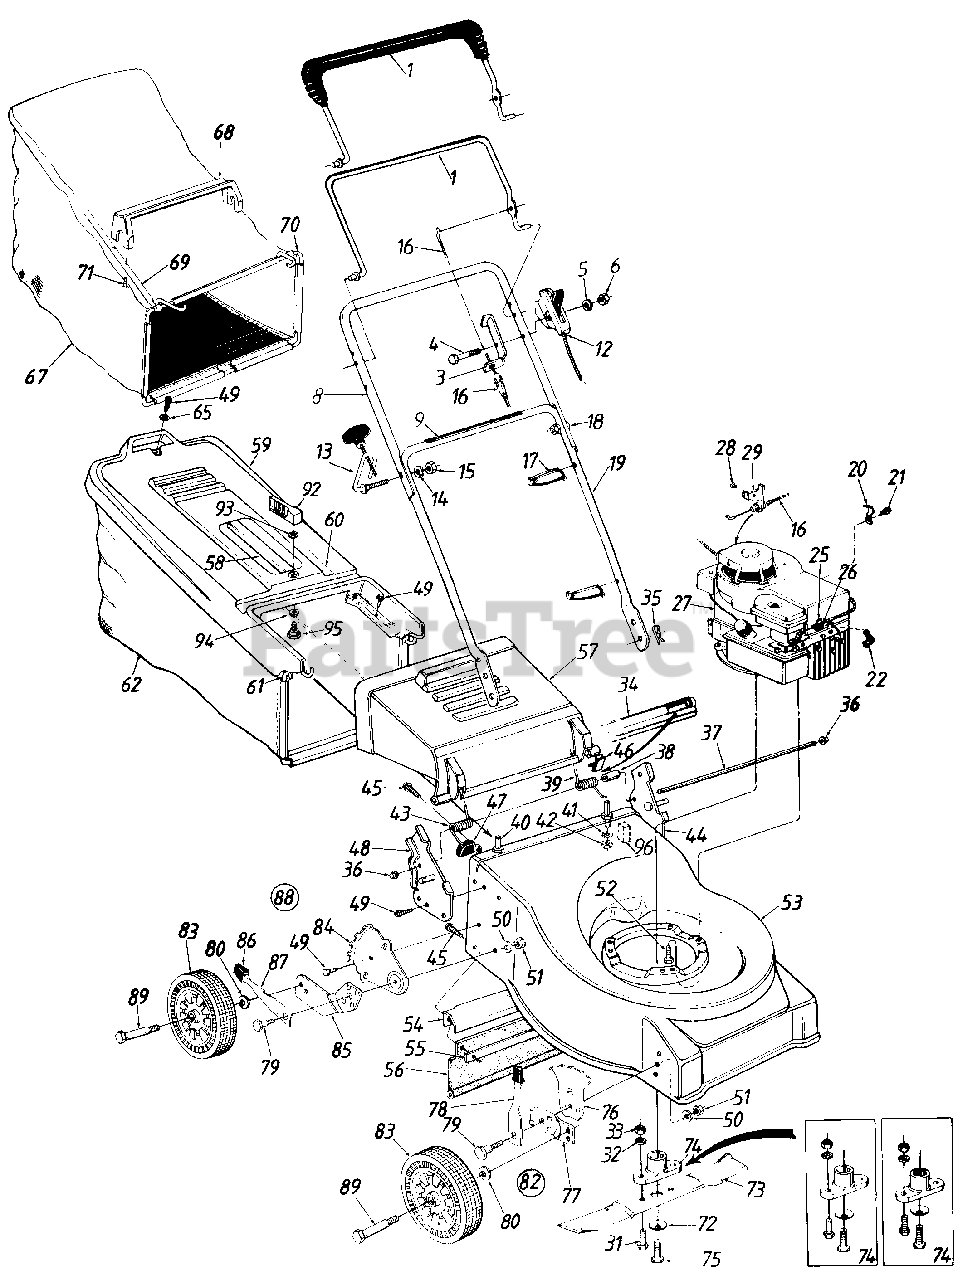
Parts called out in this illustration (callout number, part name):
1	Control Handle Ass'y.
3	Cable Brkt.
4	Hex Bolt 1/4-20 x 1.75" Lg.
5	Spr. Wash. 1/4" I.D.
6	Hex Nut 1/4-20 Thd.
12	Throttle Control Ass'y. Comp.- 56.62"
13	Rope Guide Bolt
14	L-Wash. 5/16" I.D.
15	Hex Nut 5/16-18 Thd.
16	Control Cable-43"
17	Cable Tie
18	Curved Carriage Bolt 5/16-18 x 1.38" Lg.
19	Lower Handle
20	Cable Clamp
21	Hex B-Tap Scr. #10 x .38" Lg.
22	Spark Plug Boot
25	Cable Clamp
26	Hex AB-Tap Scr. #8 x .5" Lg.
27	Engine
28	Pop Rivet .156" Dia.
29	Cable Bracket
31	Hex Bolt 3/8-24 x 1
32	L-Wash. 3/8" I.D.
33	Hex Nut 3/8-24 Thd.
34	Seal-Extrusion
35	Int. Cotter Pin 5/16" Dia.
36	Cap Speed Nut
37	Hinge Pin 17.75" Lg.
38	Spacer.255" I.D.
39	Torsion Spring-L.H.
40	Shld. Pin 3/8-24 x 1.43" Lg.
41	L-Wash. 3/8" I.D.
42	Hex Jam Nut 3/8-24 Thd.
43	Torsion Spring-R.H.
44	Handle Brkt. Ass'y.-L.H.
45	Torx Mach. AB-Tap Scr. 1/4 x .62" Lg.
46	Deflector Plug
47	Corner Plug
48	Handle Brkt. Ass'y.-R.H.
49	Hex L-Wash. AB-Tap Scr. 1/4 x .62" Lg.
50	Bell-Wash. .39" I.D.
51	Hex Nut 3/8-16 Thd.
52	Hex L-Wash. Hd. Scr. 3/8-16x 1" Lg.
57	Rear Chute Deflector
58	Hardtop Handle
59	Hardtop Bag Cover
60	Rear Catcher Frame
61	Front Catcher Frame
62	Grass Bag
65	Fl-Wash. .281" I.D.
67	Grass Bag
68	Bag Handle
70	Front Catcher Frame
71	Hex AB-Tap Scr. #12 x 1.25" Lg.
72	Bell-Wash. .39" I.D.
73	21" Blade
74	Blade Adapter Kit (Keyed)
75	Hex Bolt 3/8-24 x 1.5" Lg.
76	Height Adj. Plate
78	Spring Lever Ass'y. w/Knob
79	Shld. Bolt .50" Dia. x .357"
80	Bell-Wash. .38" I.D. x .88" O.D.
82	Height Adj. Ass'y. Comp.-R.H.
83	Wheel Ass'y. Comp.
84	Index Plate
85	Pivot Bar-R.H.
86	Spring Lever Knob
87	Spring Lever
88	Rear Height Adj. Ass'y. Comp.-R. H .
89	Axle Bolt
92	Grass Catcher Locking Knob
93	Internal L-Wash. 1/4" I.D.
94	Wave Washer 3/8" I.D.
95	Shld. Bolt .342" Dia. x .268"
